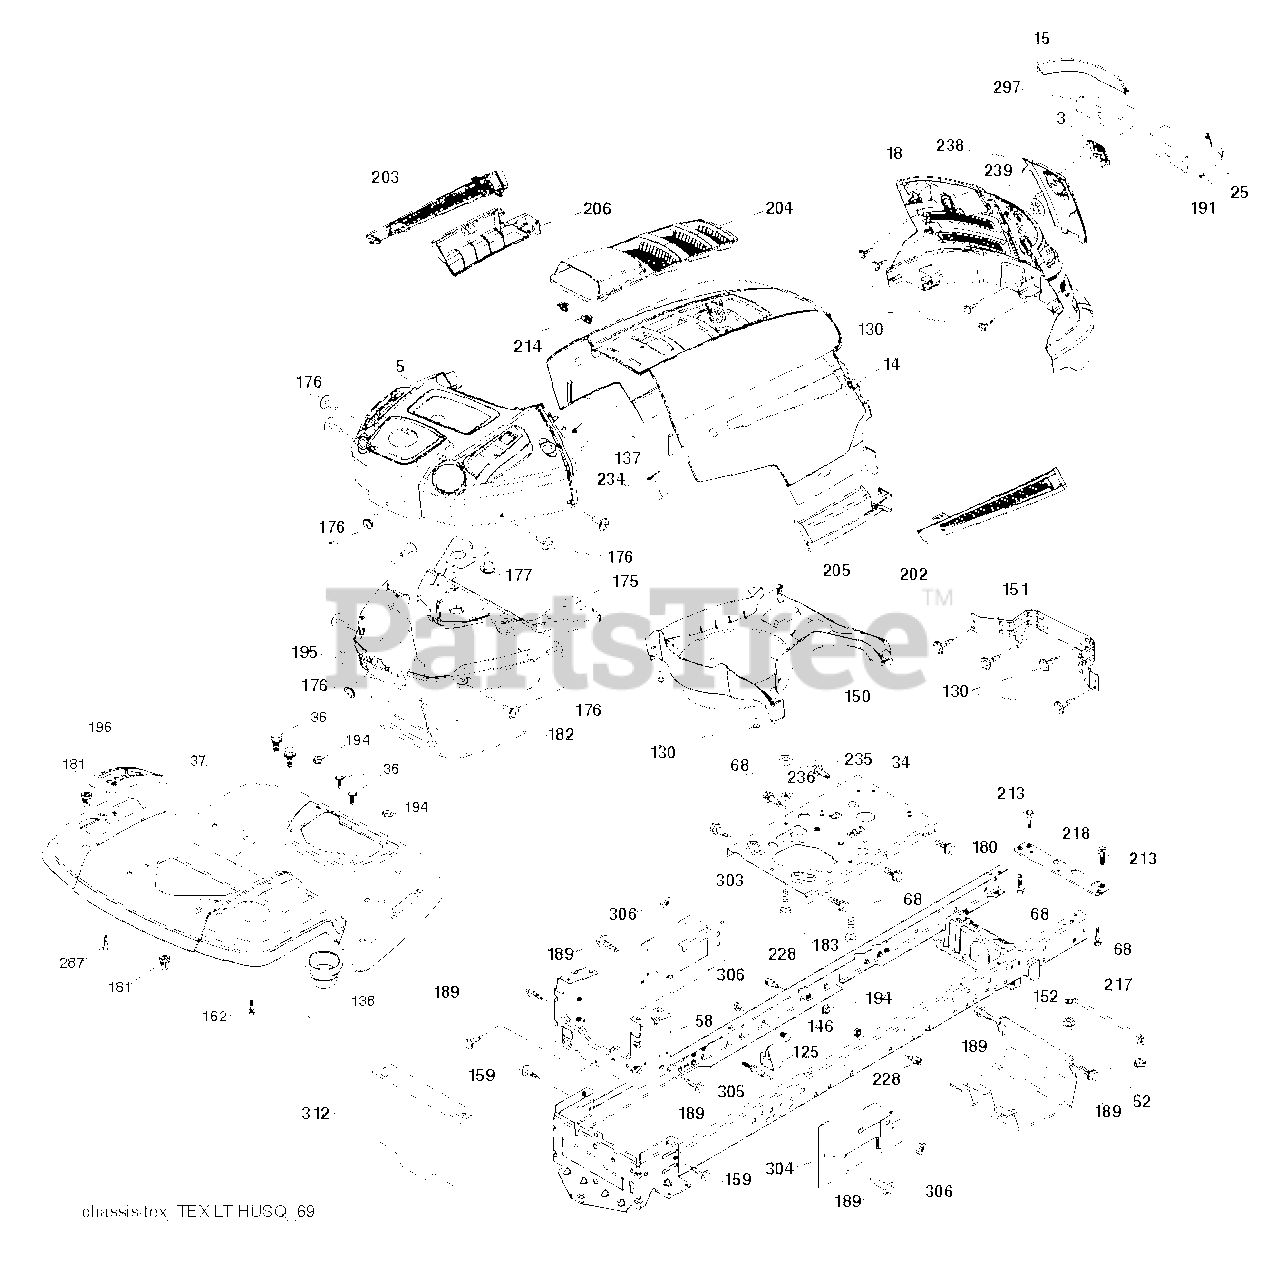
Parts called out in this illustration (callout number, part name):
3	LOGO.HUSQ.GT.LT.CROWN.H
5	DASH.ASM.UPPER.W/BPR.HUSLT.498
14	HOOD.HUSQVARNA.LT.ORANGE
15	LENS.HUSQVARNA LT.RH
18	GRILLE.SVC.HUSQVARNA.GREY
25	LENS.HUSQVARNA LT.RH
34	PLATE.ENGINE.WELDED.CHASSIS
36	SCREW 5/16"
37	FENDER.TLT.FS.W/CUPHLD.ORANGE
52	LOCKNUT
58	DRAWBAR UPPER 2PC SMALL FENDER
68	SCREW LT
125	CLIP.FUEL.LINE
130	SCREW.#10 X 0.750.BOS
137	BUMPER DASH
138	CUPHOLDER.TL.TEX.BLACK
146	BOLT.RDHD.SHT.SQNK.3/8-16X5/8
151	BRACKET PIVOT
152	SHIELD.BROWNING.W/TEX
159	SCREW, 3/8-16X3/4
162	SCREW.HI-LO.CONSOLE
175	CROSSMEMBER
176	SCREW.#10-24X5/8.RN.QU
177	BUSHING STEERING
180	CHASS.WLDMNT.TL.12GA/2P.48/54
181	BUSHING.MNT.FEND.CRGO.
182	DASH.LOWER.PREDATOR LT
183	BOLT.5/16-18X1-1/4 FULL THD
189	SCREW
191	INSERT.REFLECTIVE.RH.
194	NUT LOCK HEX FLANGE 5/16-18
195	PLUG.TEX.DASH.SVC.MINDER.GREY
196	CONSOLE.ASM.DECKLFT.BL/RBT.TLT
202	VENT.SIDE.HUSQVARNA.LT.RT
203	VENT.SIDE.HUSQVARNA.LT.LFT
204	SUBASM.TOP.VENT.HUSQ.LT
205	SKIRT.SIDE.HUSQVARNA.LT.RT
206	SKIRT.SIDE.HUSQVARNA.LT.LEFT
213	BOLT
214	CLIP.RETAINER.TINNER.
217	ROD.PIVOT.HOOD
218	X-PIECE.HOOD.STOP.NON/
228	STUD.FASTNER.W/ANTI-ROTATE
234	BUMPER.HOOD.TEX.HUSQVARNA
235	SPACER FENDER
236	NUT.CENTERLOCK.5/16-
238	TRIM.HUSQ LT.668
287	SCREW 1/4X20
297	INSERT REFLECTIVE
303	SHIELD CHASSIS LEFT
304	SHIELD CHASSIS RIGHT
306	NUT LOCK FLG 3/8-16 UNC
312	SHIELD.PNT.DRAWBAR.FRENCH
